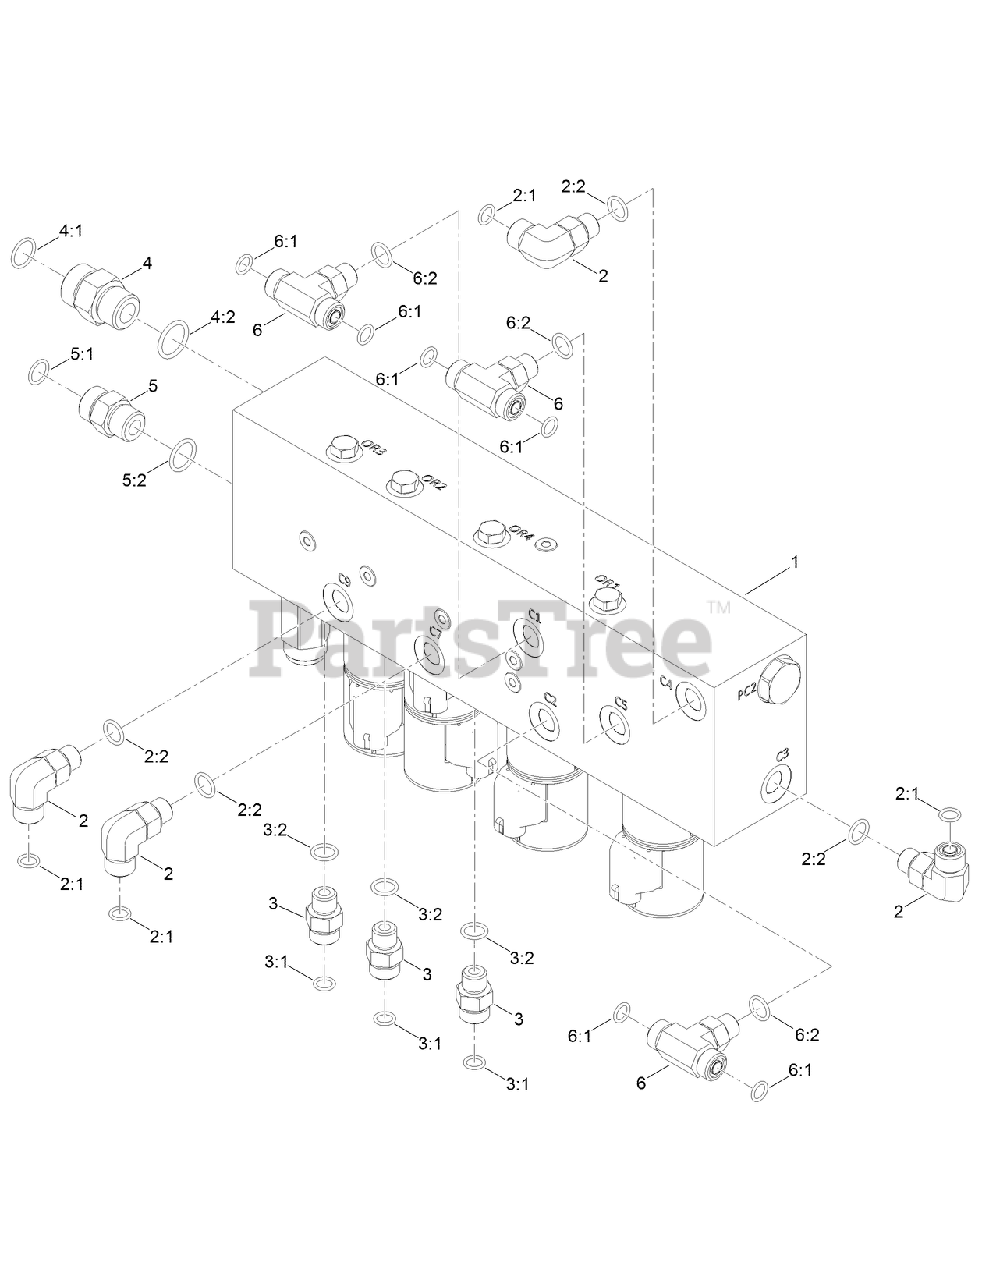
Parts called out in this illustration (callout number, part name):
1	LOADING MANIFOLD ASM
2	FITTING-ELBOW, 90 DEG
2:1	O-RING
2:2	O-RING
3	FITTING-STRAIGHT
3:1	O-RING
3:2	O-RING
4	FITTING-STRAIGHT
4:1	O-RING
4:2	O-RING
5	FITTING-STRAIGHT
5:1	O-RING
5:2	O-RING
6	ADAPTER
6:1	O-RING
6:2	O-RING
